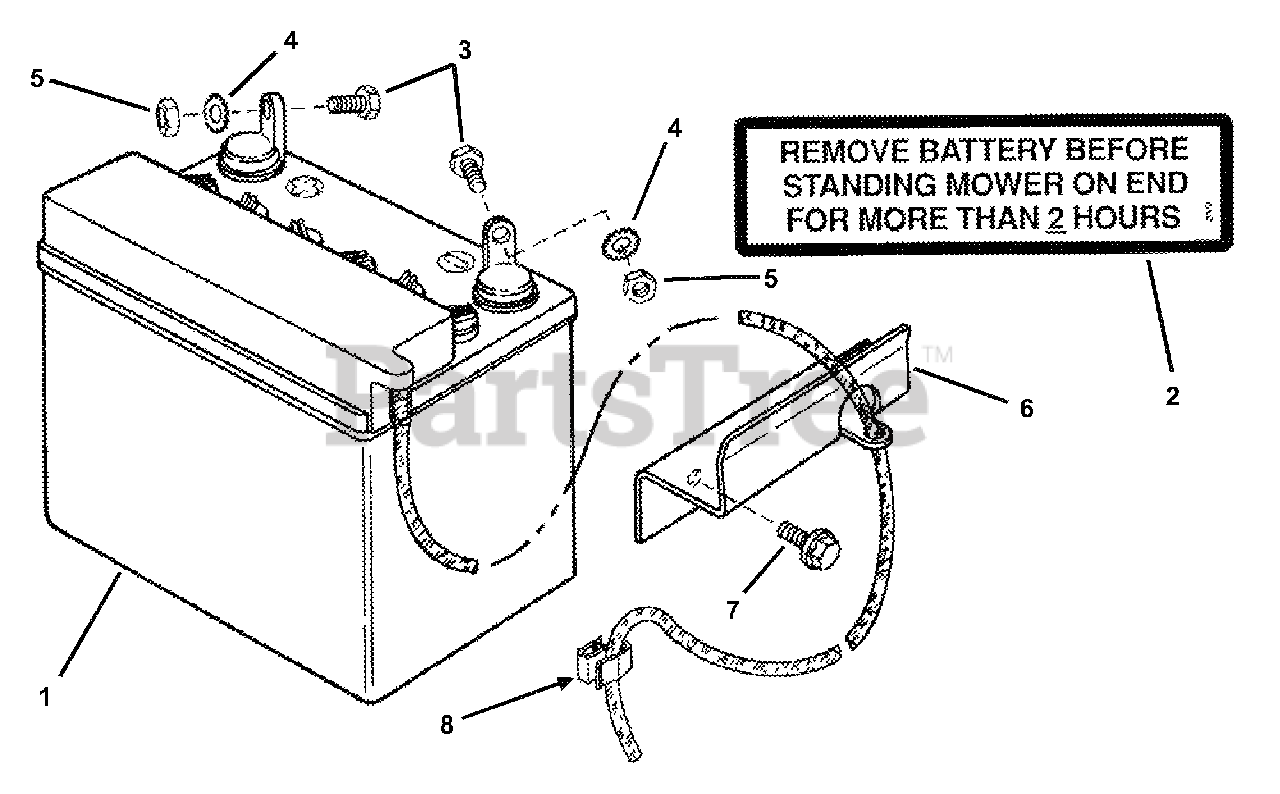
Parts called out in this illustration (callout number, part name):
1	BATTERY, No-Spill, Lead/Acid Dry Charge Type
2	DECAL, Battery
3	SCREW, 1/4-20 x 5/8" Hex Head Cap
4	RETAINER, 1/4" Bolt
5	NUT, 1/4-20 Hex Center Lock
6	CLAMP, Battery Retaining
7	SCREW, 5/16-18 x 1/2" Hex Washer Self-Tapping
8	CLAMP, Battery Hose
